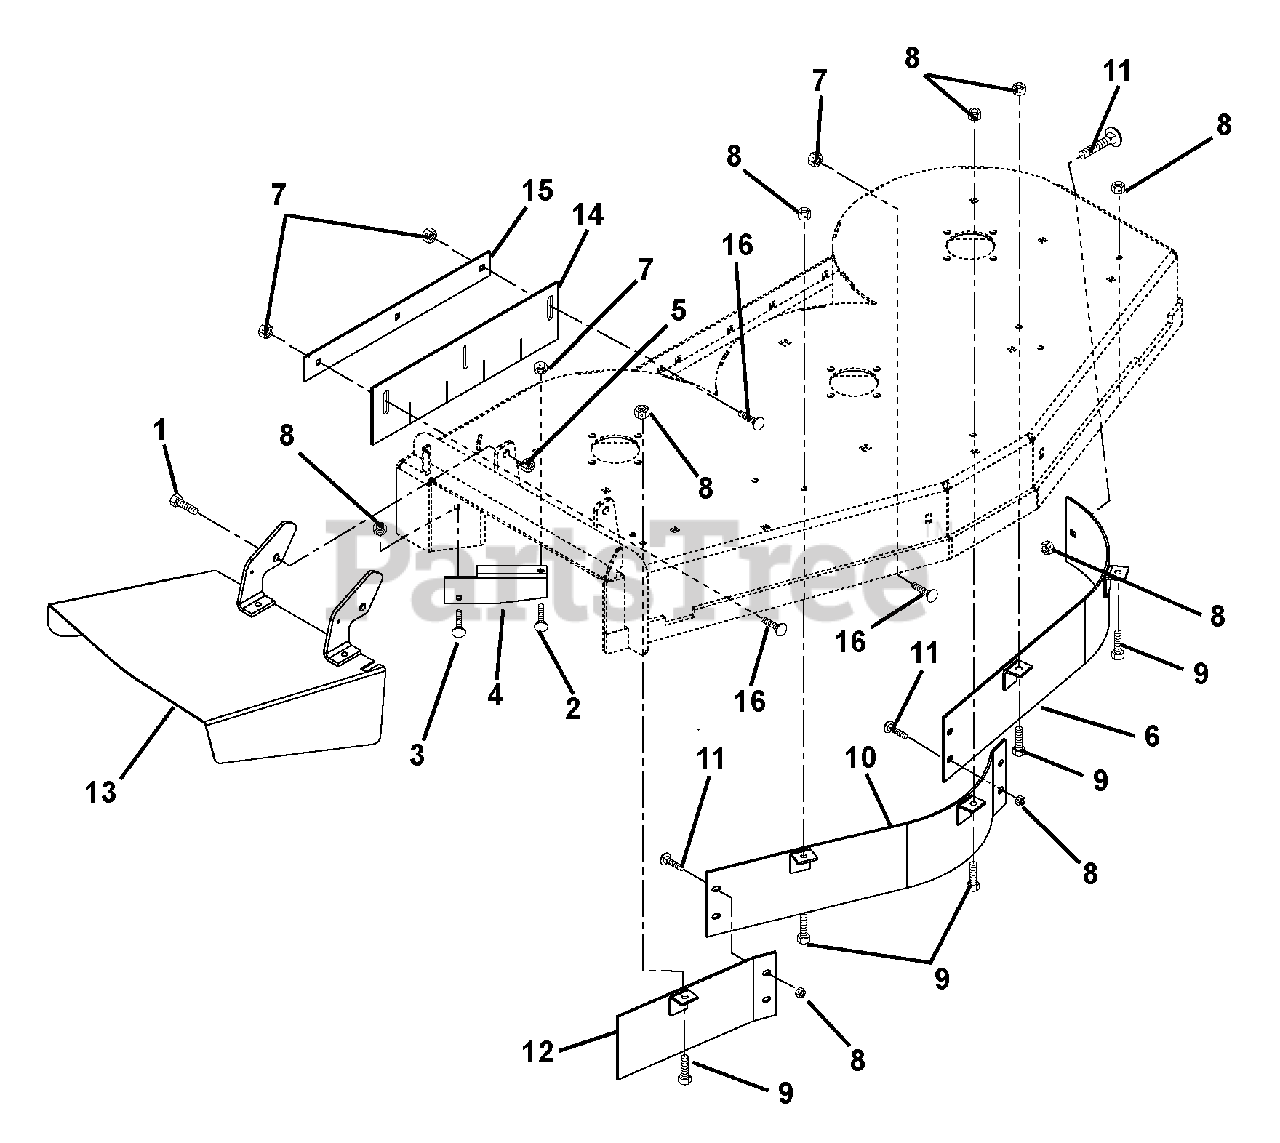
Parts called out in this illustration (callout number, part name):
1	@BLT-HEX .50-13X1.25 GR5 YWZC
2	@BLT-RDHDSQNK .38-16X.75 G5YZ
3	@BLT-RDHDSQNK .31-18X.75 G5YZ
4	DEFLECTOR - 44"/48"
5	@NUT-LK-NYL .50-13 YWZC
6	BAFFLE - LEFT FRONT - 48"
7	@NUT-LK-TOP-FLG .38-16 YWZC
8	@NUT-LK-TOP-FLG .31-18 YWZC
9	@BLT-HEX .31-18X.75 GR5 YWZC
10	BAFFLE - CENTER FRONT - 48"
11	@BLT-RDHDSQNK .31-18X.75 G5YZ
12	BAFFLE - RIGHT FRONT - 48"
13	WMT - DISCHARGE CHUTE - PRO
14	SKIRT- RUBBER
15	STRIP - STRIPER MOUNT
16	@BLT-RDHDSQNK .38-16X1.00 G5YZ
